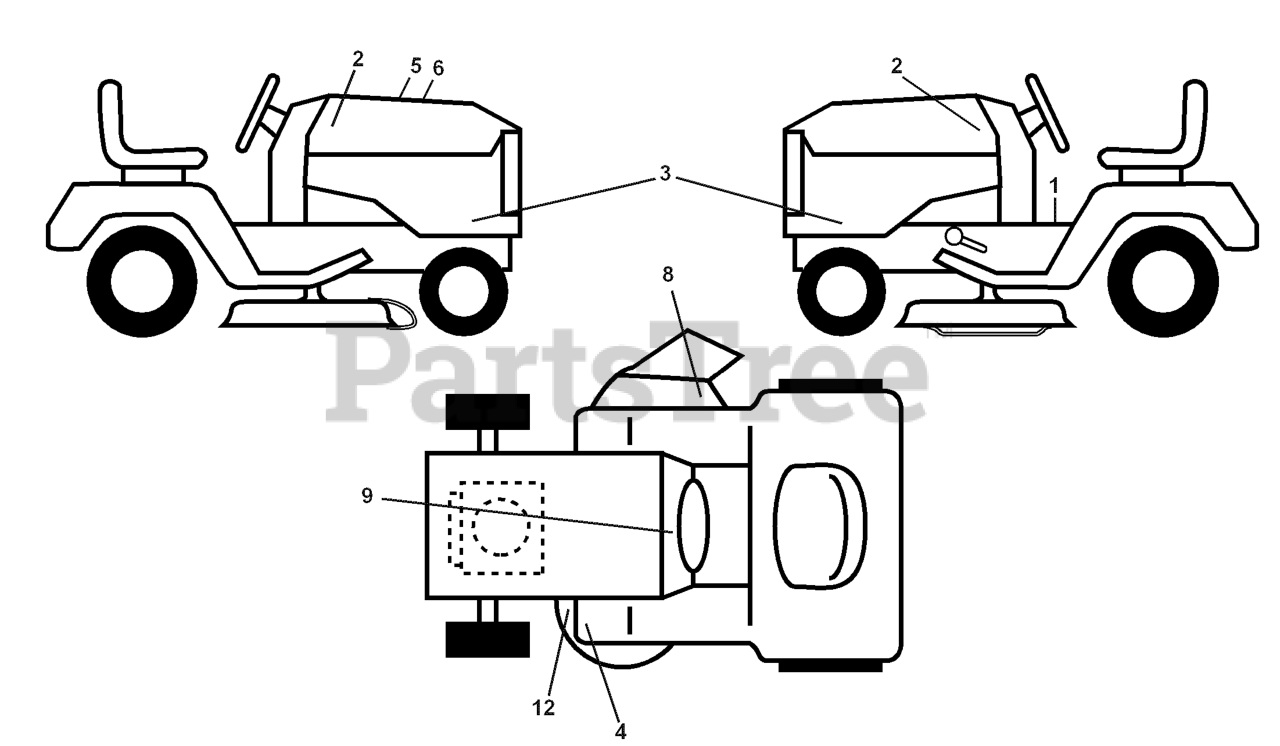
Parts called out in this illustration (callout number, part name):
1	DECAL.FENDER.WARNING.ENG
2	EMBLEM.HOOD.HUSQ.DEALER
3	DECAL.SDPNL.2346XLS.VANGRD.HU
4	DECAL.PEDAL.HUSQ.CROWN
5	DECAL HOOD CUST. RESP.
6	DECAL.RPL.BSM38.VAGD.TLW46K46
8	DECAL.WARN.KEEP.HAND.AWAY
9	DECAL BTRY SYMBOLS
12	DECAL V BELT SCHEMATIC
